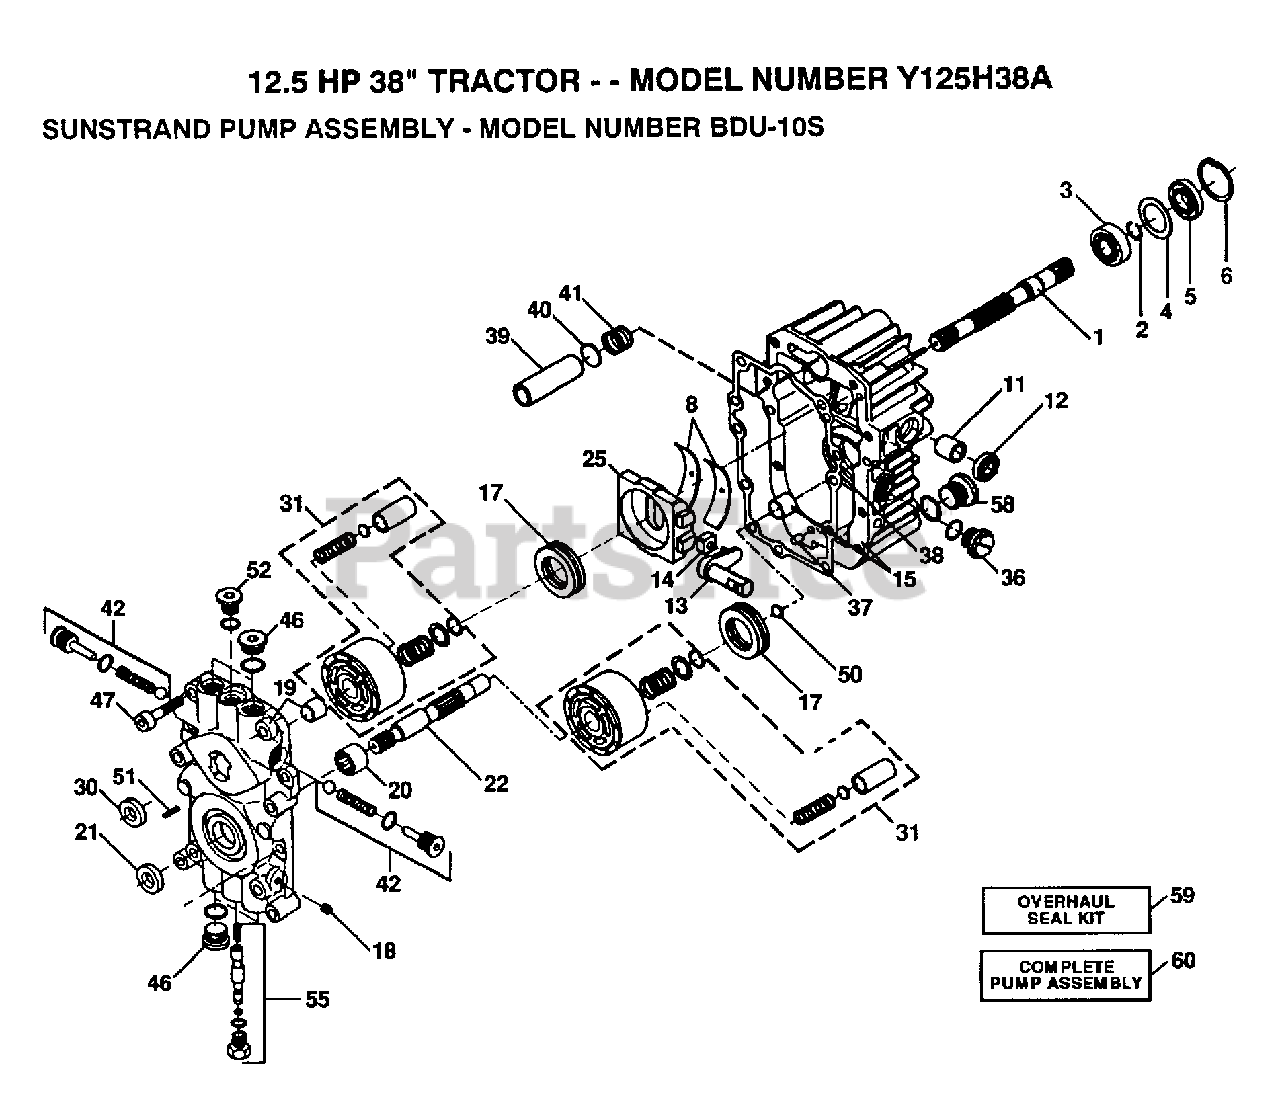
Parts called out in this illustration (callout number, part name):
1	SHAFT.PU.2003022
2	RETAINIANG RING-(2003016)
3	BALL BEARING
4	SPACER
5	SEAL LIP
6	RING.RET.2003052
8	CRADLE BEARING (2003023)
11	BEARING
12	SEAL.9008000-0126
13	TRUNION ARM (2003005)
14	GUIDE.2000015.HYD
18	PLUG PIPE
19	"KIT,CTR SECTION (2513007)"
20	NEEDLE BEARING
21	LIP SEAL-9008000-0127
22	SHAFT
25	"SWASHPLATE,VARIAB"
30	SEAL LIP
31	"KIT,BLOCK CYLINDE"
36	"PLUG,PLASTIC 9005200-8700"
37	PIN
38	GASKET.20030600
39	FILTER
40	WASHER (2000011)
41	SPRING
42	KIT.VALVE.2513014
46	PLUG
47	SCREW9007314-0808
50	WASHER
51	PIN
52	PLUG
55	"KIT,BYPASS VALVE"
58	PLUG
59	"KIT,OVERHEAD SEAL -2513013"
60	PUMP.BDU-10S-114
